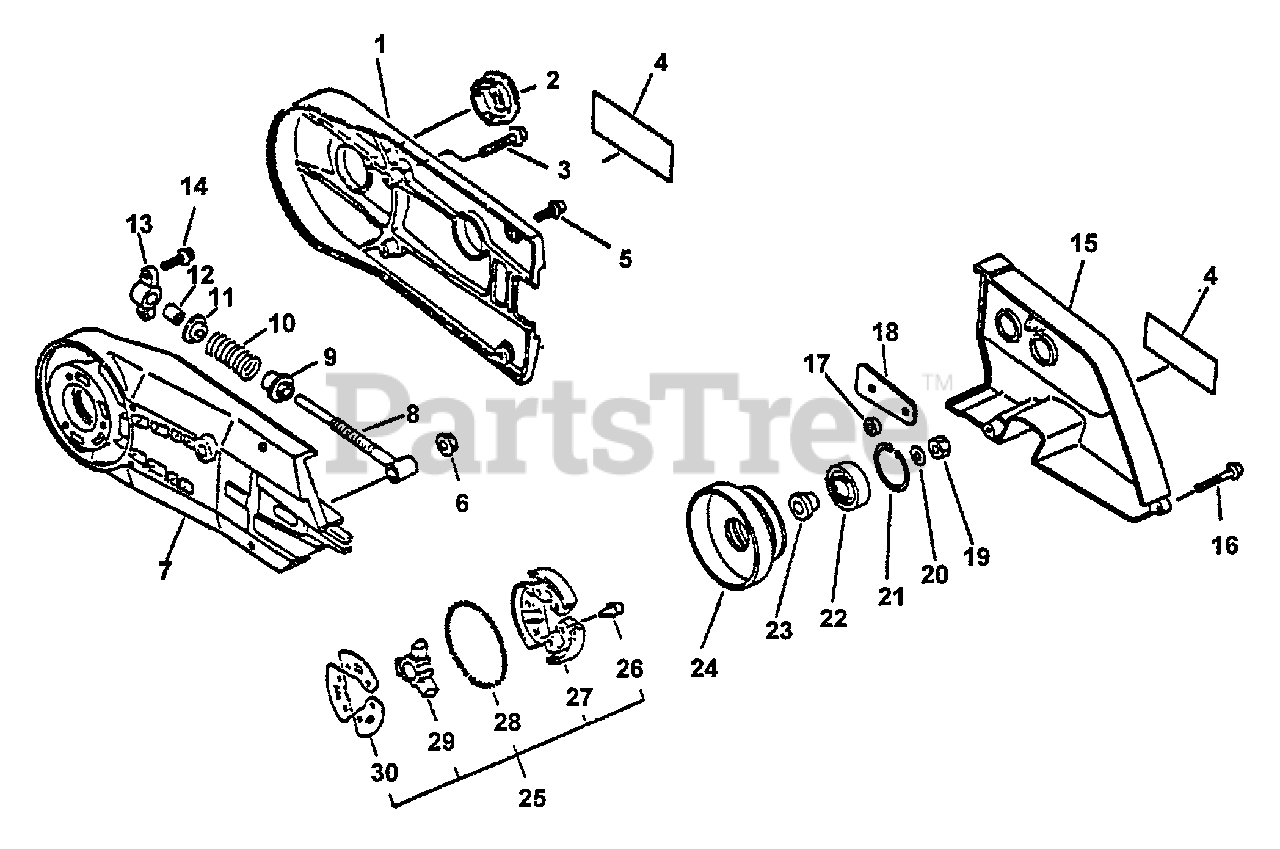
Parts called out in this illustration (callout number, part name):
1	COVER, V-BELT
3	SCREW 5×30
4	LABEL - ECHO
5	SCREW - 5×20
6	NUT, FLANGE M8×1.25
7	COVER, V-BELT
8	ROD, ADJUSTER
9	ADJUSTER
10	SPRING, ADJUSTER
11	SPRING
12	SPACER, SHAFT
13	SUPPORT
14	BOLT 5×20
15	COVER, ARM
16	SCREW 4×35
18	SPACER, ARM
19	NUT 8 LH
20	WASHER, CLUTCH
21	RING, SNAP Ø32
22	BEARING, BALL 6201
24	DRUM, CLUTCH
25	CLUTCH ASSY
26	BOLT 4×8
27	CLUTCH SHOE SET
28	SPRING, CLUTCH
29	BOSS, CLUTCH
30	PLATE, CLUTCH
